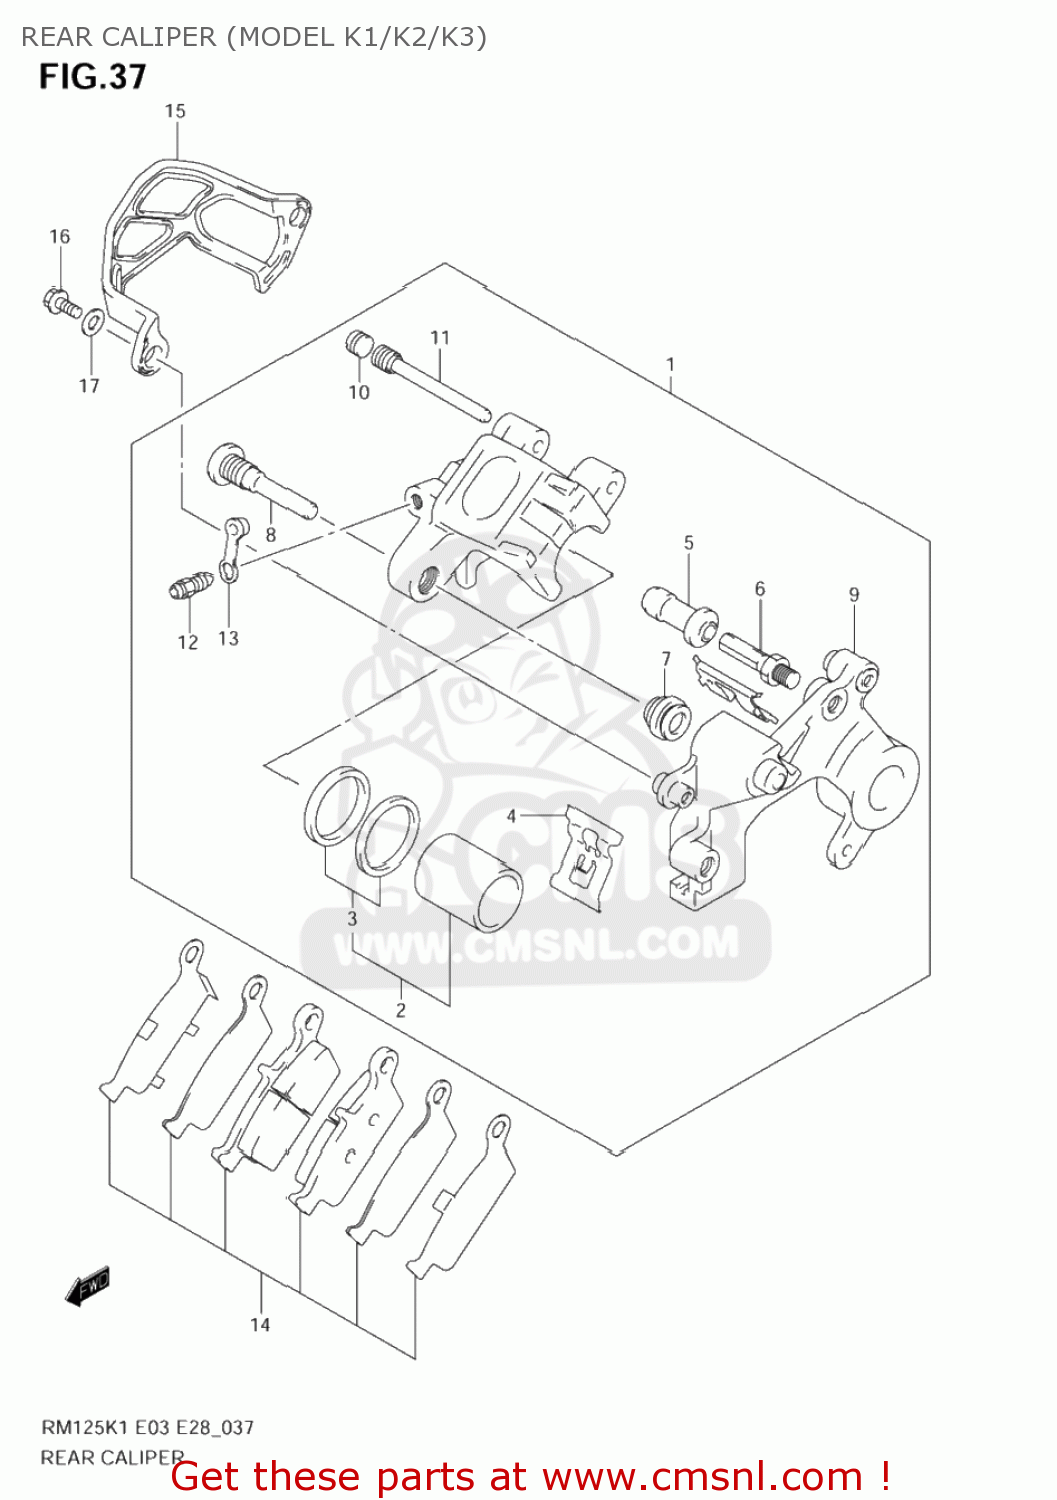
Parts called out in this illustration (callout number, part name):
1	CALIPER ASSY,RR
2	PISTON SET
3	SEAL SET,PISTON
4	SPRING,PAD
5	BOOT
6	BOLT
7	BOOT
8	PIN,BOLT
9	BRACKET
10	PLUG,PIN
11	PIN,HANGER
12	BLEEDER
13	CAP,BLEEDER
14	PAD & RETAINER SET
15	GUARD,RR CALIPER
16	BOLT
17	WASHER
